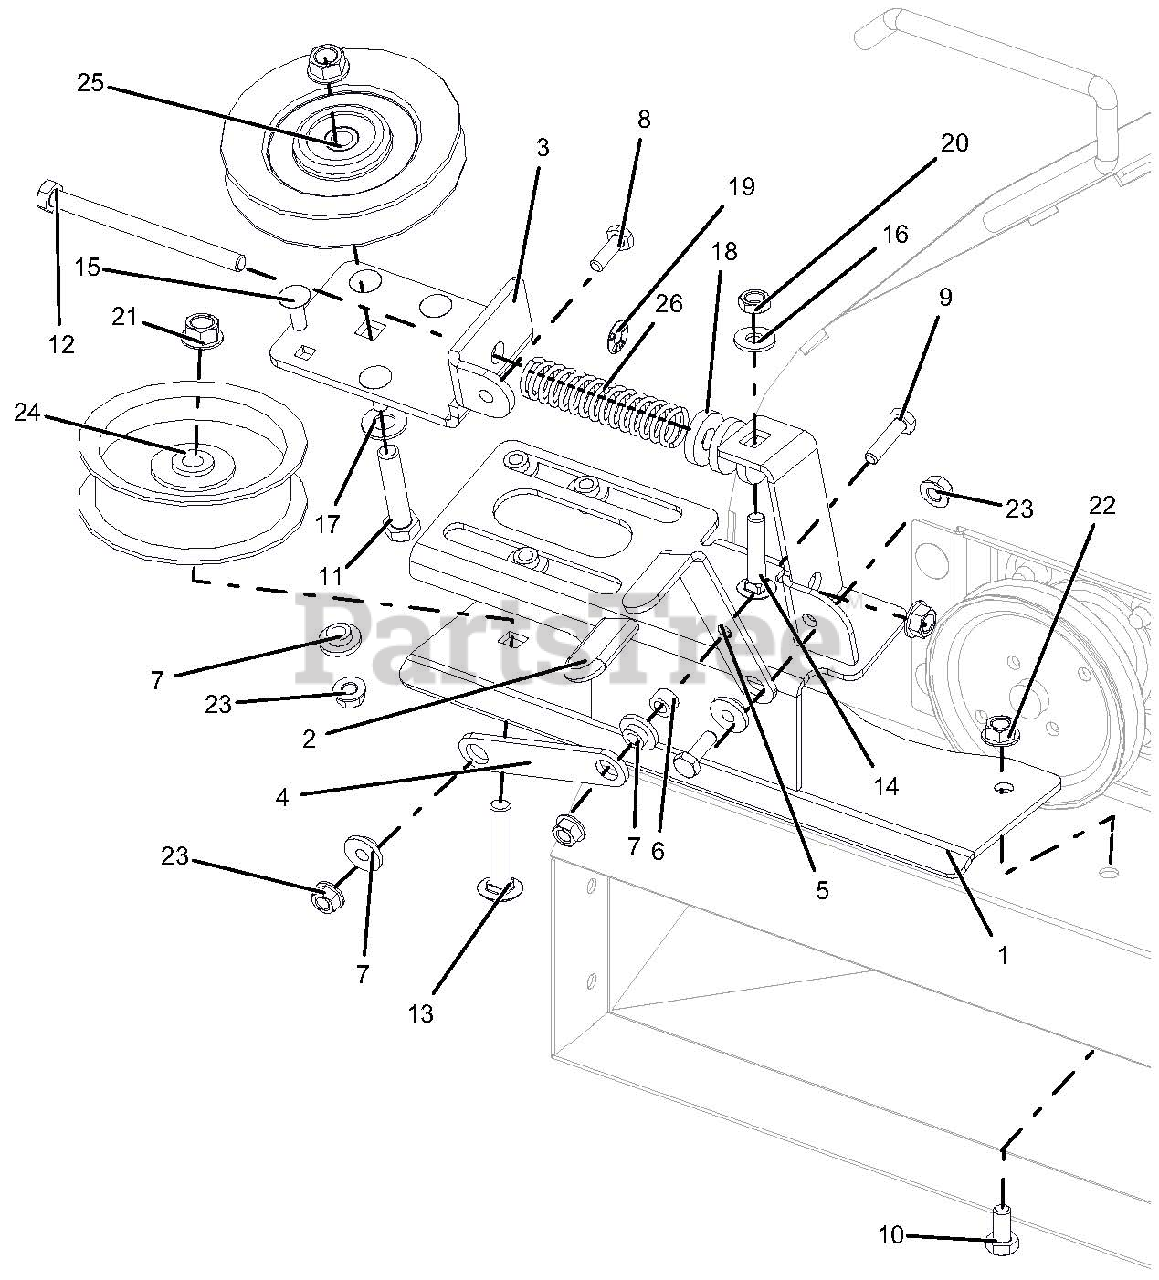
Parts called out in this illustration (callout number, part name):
1	WELDMENT, IDLER MOUNT -2015
2	GRIP, SEAT LEVER, GREY
3	BRACKET, ADJ. PULLEY IDLER
4	LINK, TENSIONER
5	HANDLE, TENSIONER
6	BUSHING, .26 ID X .44 OD X .26
7	BSHG-FLG .265X.437X.250X.750
8	@BLT-HEX .25-20X.75 GR5 YWZC
9	@BLT-HEX .25-20X1.00 GR5 YWZC
10	BLT-HEX .31-18X.63 GR5 YWZC
11	@BLT-HEX .38-16X1.75 GR5 YWZC
12	@BLT-HEX .31-18X4.00 GR5 YWZC
13	@BLT-RHDSSQNK .38-16X1.75 G5YZ
14	@BLT-RDHDSQNK .31-18X1.50 G5YZ
15	@BLT-RDHDSQNK .25-20X.75 G5YZ
16	@WSHR-FL-STL.312X.734X.065 YWZ
17	@WSHR-FL-STL.406X.812X.065 YWZ
18	WSHR-FL-STL .406X1.00X.188 YWZ
19	NUT-PUSH .312
20	NUT- JAM .312-18 YWZC
21	@NUT-LK-TOP-FLG .38-16 YWZC
22	@NUT-LK-TOP-FLG .31-18 YWZC
23	@NUT-LK-TOP-FLG .25-20 YWZC
24	IDLER, FLG .38ID X 3.50
25	V-IDLER, 4.00X.38
26	SG-COMP .092X.77X3.13 WLD 36
